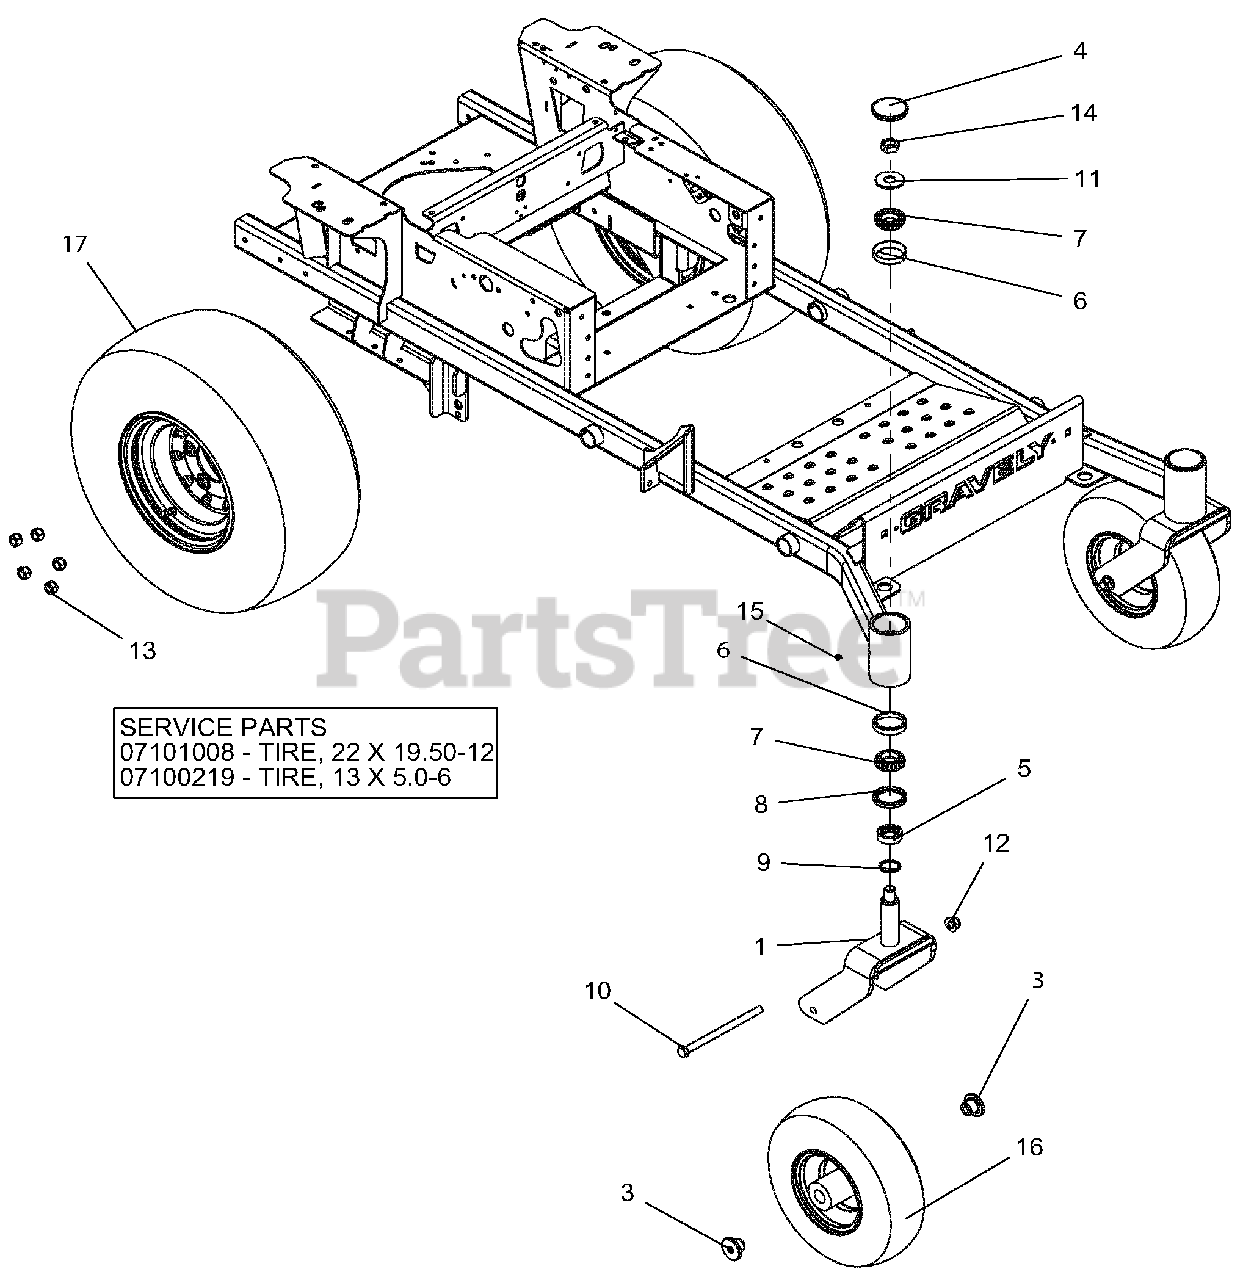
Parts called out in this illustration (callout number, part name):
1	WLDMT, CASTER FORK-RED
3	SPACER, FRONT WHEEL
4	CAP, DUST
5	SPCR, FRONT CASTER FORK
6	BRG, CUP 2.328 X .465
7	BRG, CONE 1.250 X .660
8	SEAL, OIL 1.75 X 2.332 X .312
9	O-RING, .139 W X 1.234 ID
10	BLT-HEX .50-13X7.50 GR5 YWZC
11	WSHR-FL-STL.812X2.00X.148YWZC
12	NUT-LK-NYL-FLG .50-13 YWZC
13	NUT, LUG .500-13
14	@NUT-LK-CTR-JAM .75-16 YWZC
15	PLUG, .250-28 X .185 HEX HEAD
16	TIRE/WHEEL, ASM, 13X5-6
17	TIRE/WHEEL, ASM 22X10-10
